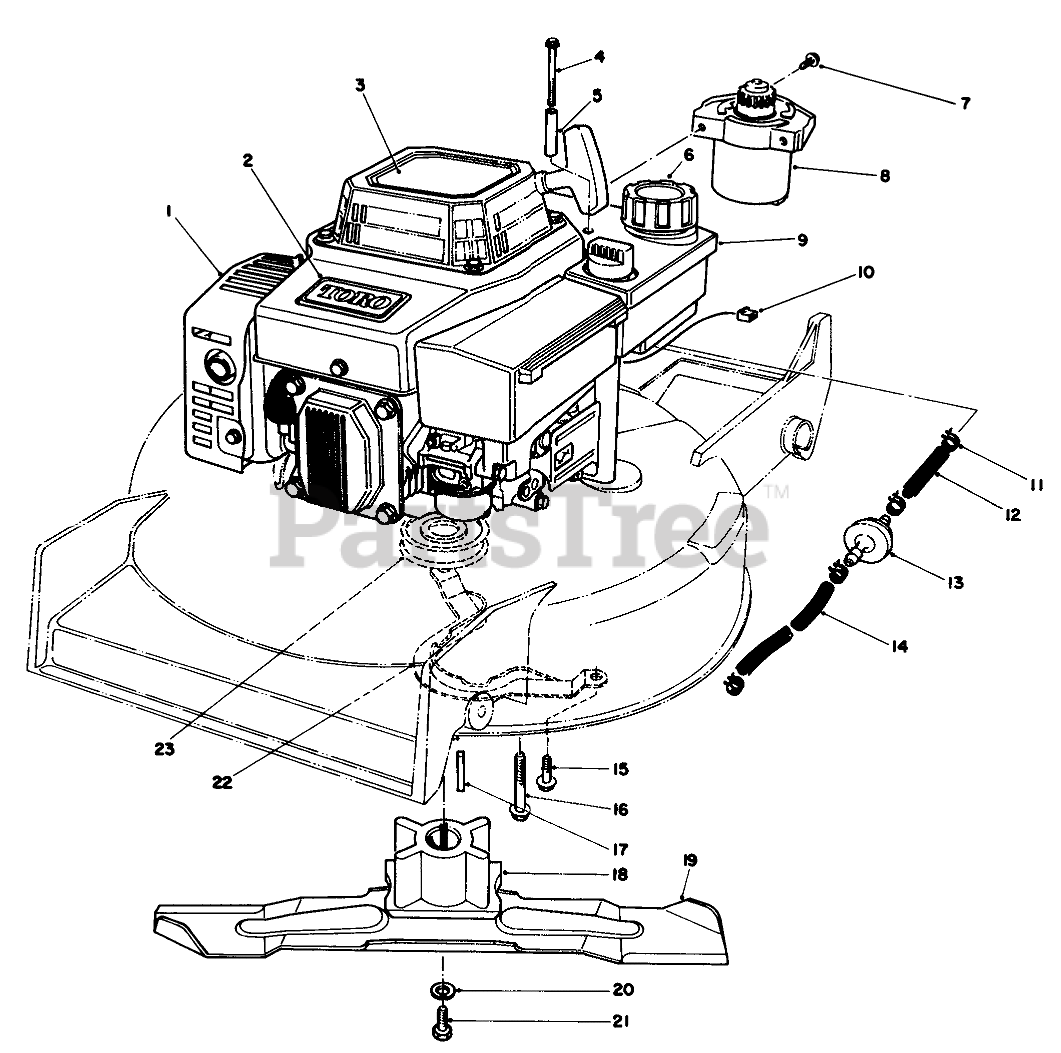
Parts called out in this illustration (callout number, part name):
1	Engine
2	TORO LOGO PLT
3	DECAL-HV INT'L
4	THRD FORMING SCREW
5	TUBULAR SPACER
6	GAS CAP ASM
7	SCREW
8	STARTER MOTOR ASM
9	TANK ASM
10	CONNECTOR BODY
11	CLAMP-FUEL LINE
12	LINE-GAS
13	FILTER-FUEL
14	HOSE-FUEL
15	Screw
16	SCREW-HWHTF
17	KEY-SQUARE
18	Retainer Blade
19	BLADE-21in
20	WASHER-LOCK
21	SCREW-BLADE
22	BELT GUIDE
23	PULLEY-DRIVER
